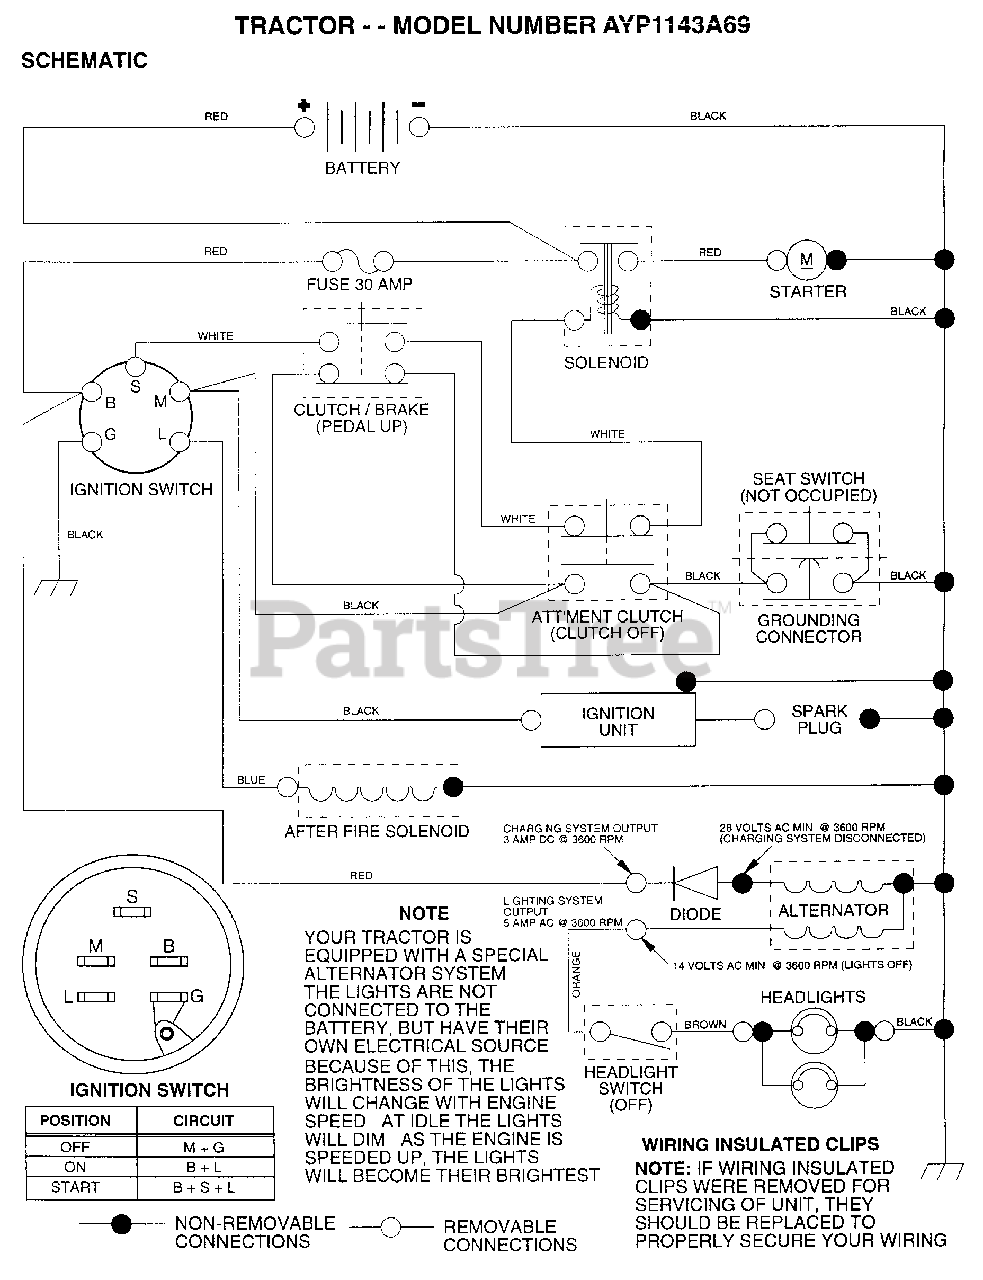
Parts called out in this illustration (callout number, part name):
2	BOLT LT
3	WASHER
4	LOCKWASHER
7	TUBE T
9	HOSE CLAMP T
15	FASTNER.SNAP-IN
20	NUT
21	"HARNESS,LIGHT SOC"
22	HEADLAMP BULB
24	"CABLE T, BATTERY"
25	CABLE.BTRY.6GA.RD
26	FUSE HYT
28	CABLE T
29	SWITCH SEAT
30	SWITCH IGN 4POS
31	NUT IGNITION
32	COVER KEY SWITCH
33	KEY
35	BRACKET LT
36	SCREW
38	BRACKET SWITCH IN
39	SWITCH INTERLOCKT
40	HARNESS.IGNITION
41	BOLT HXHD FIN
44	NUT
48	ADAPTER AMMETER
52	PROTECTION LOOP
70	HARNESS ENGINE
